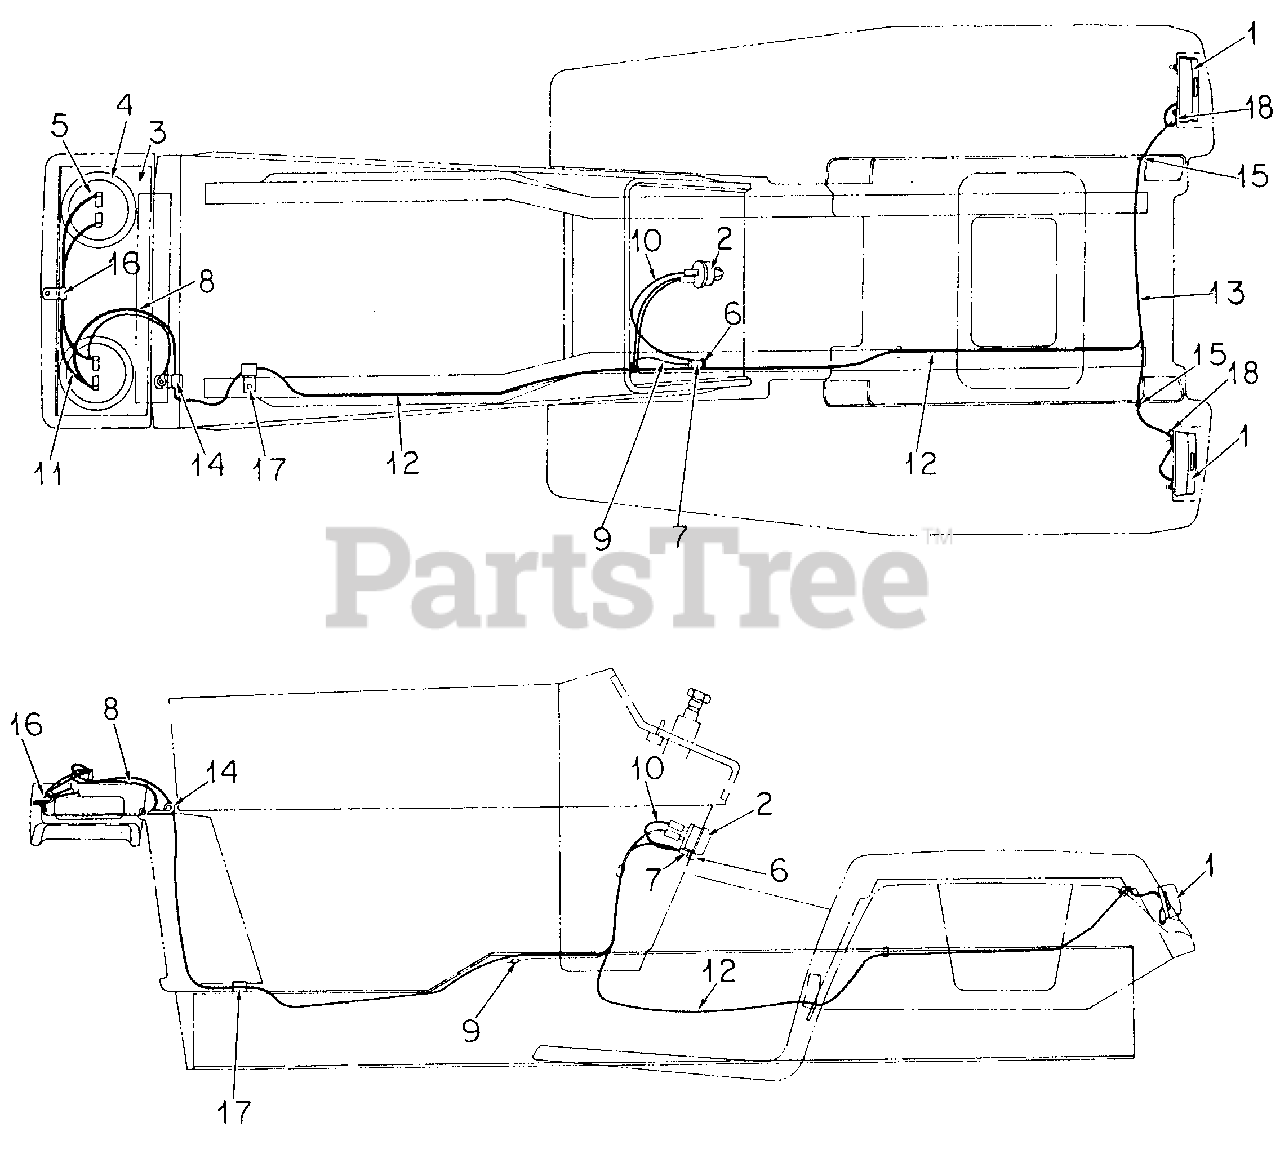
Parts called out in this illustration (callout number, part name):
1	Taillight Assy
2	Switch, Lighting
3	Panel, Headlight Mounting
4	Rim, Headlight Mounting
5	Unit Assy, Headlight Sealed Beam
6	Holder, Fuse
7	Fuse, 10 Amp
8	Cable, Headlight to Ground
9	Cable, Diode to Fuse
10	Cable, Fuse to Lighting Switch
11	Cable, Lighting
12	Cable, Headlight
13	Cable, Taillight
14	Clip, Cable
15	Clip, Cable
16	Clip, Cable
17	Clip, Cable
18	Clip, Taillight
